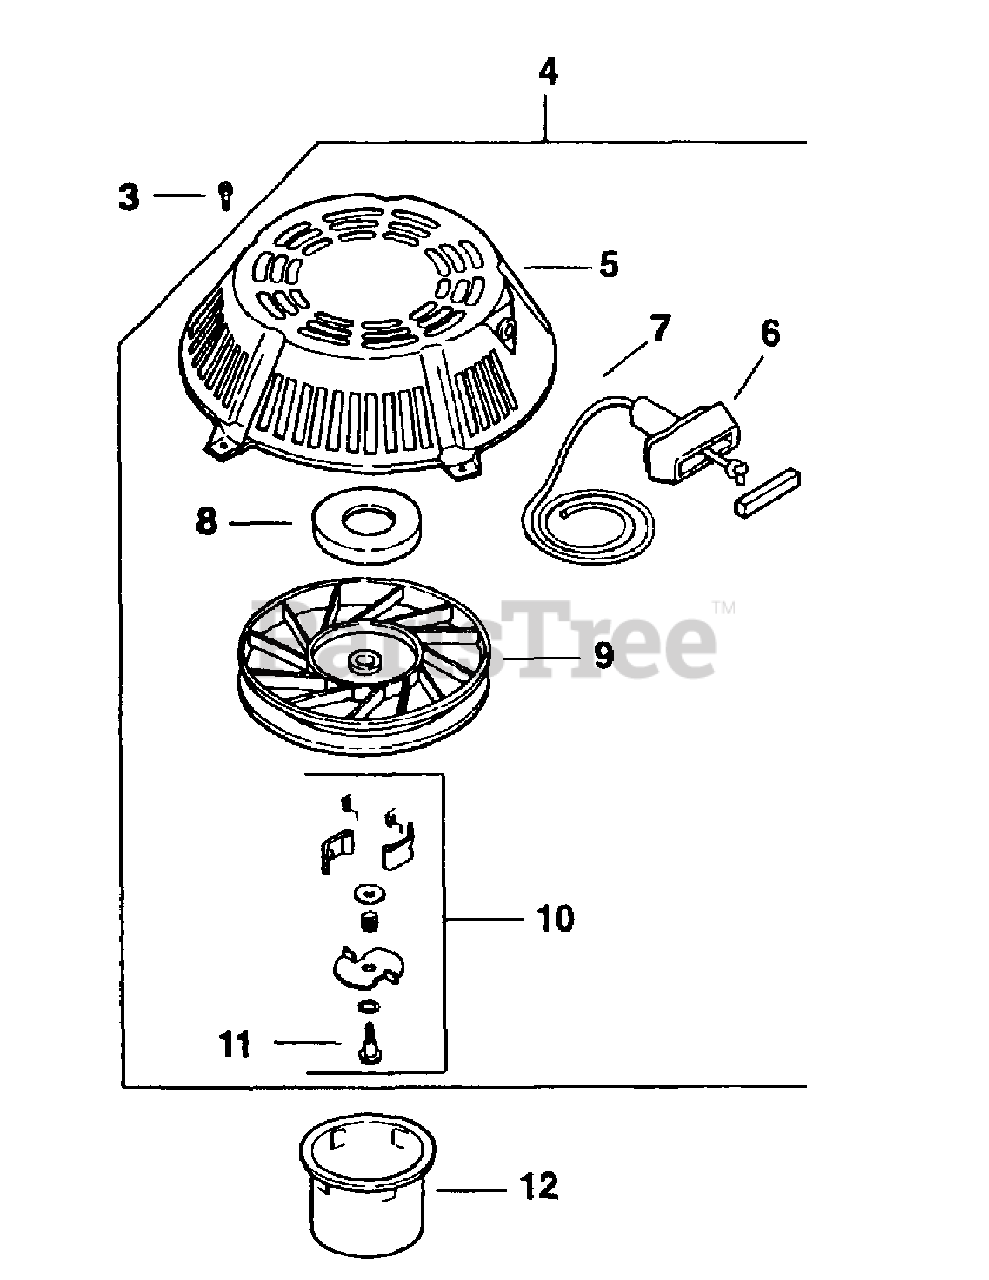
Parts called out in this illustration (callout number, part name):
3	Screw, Hex Flange
4	Starter, Retractable Assy.
5	Housing, Starter
6	Handle, Recoil Start
7	Rope, Starter
8	Spring & Keeper
10	Kit, Dog Repair
11	Screw, Pozidriv
12	Cup, Drive
